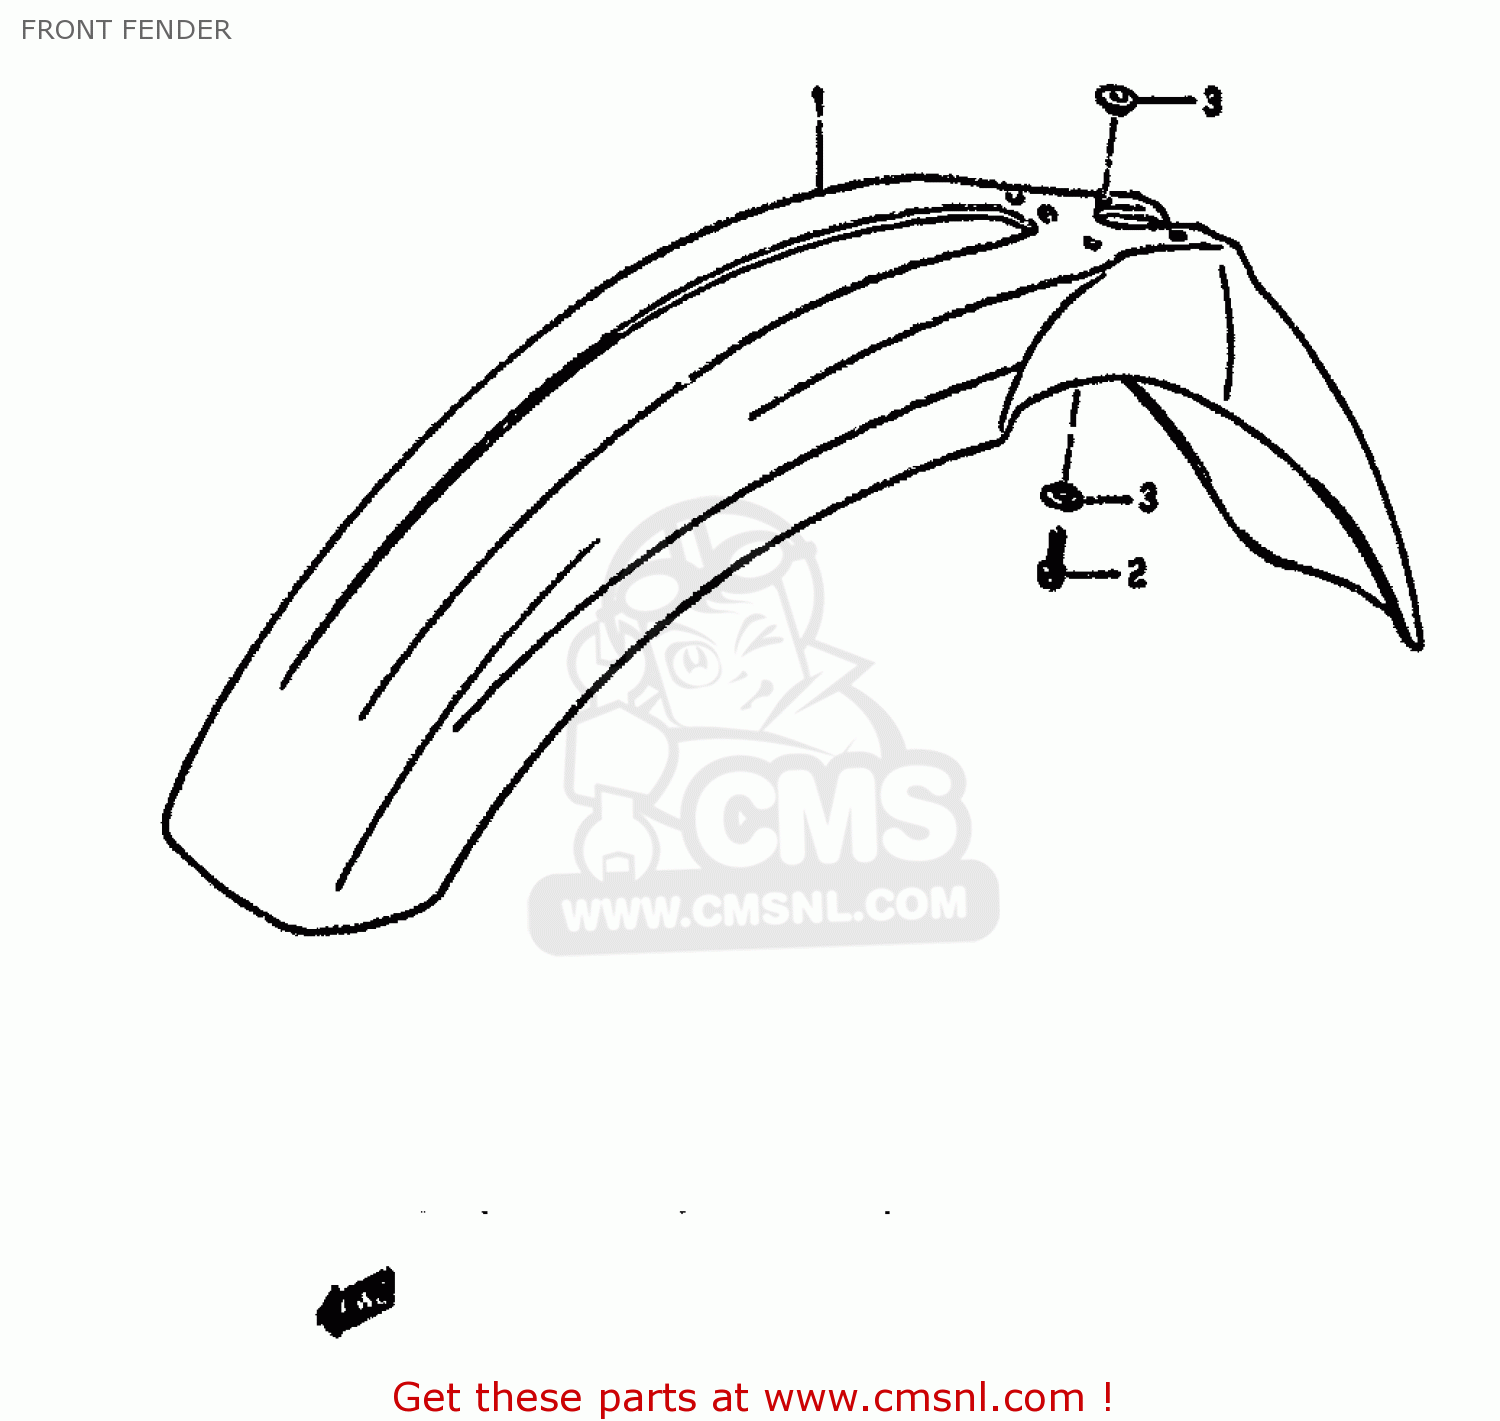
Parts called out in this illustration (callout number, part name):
1	FENDER,FRONT
2	BOLT
3	WASHER
